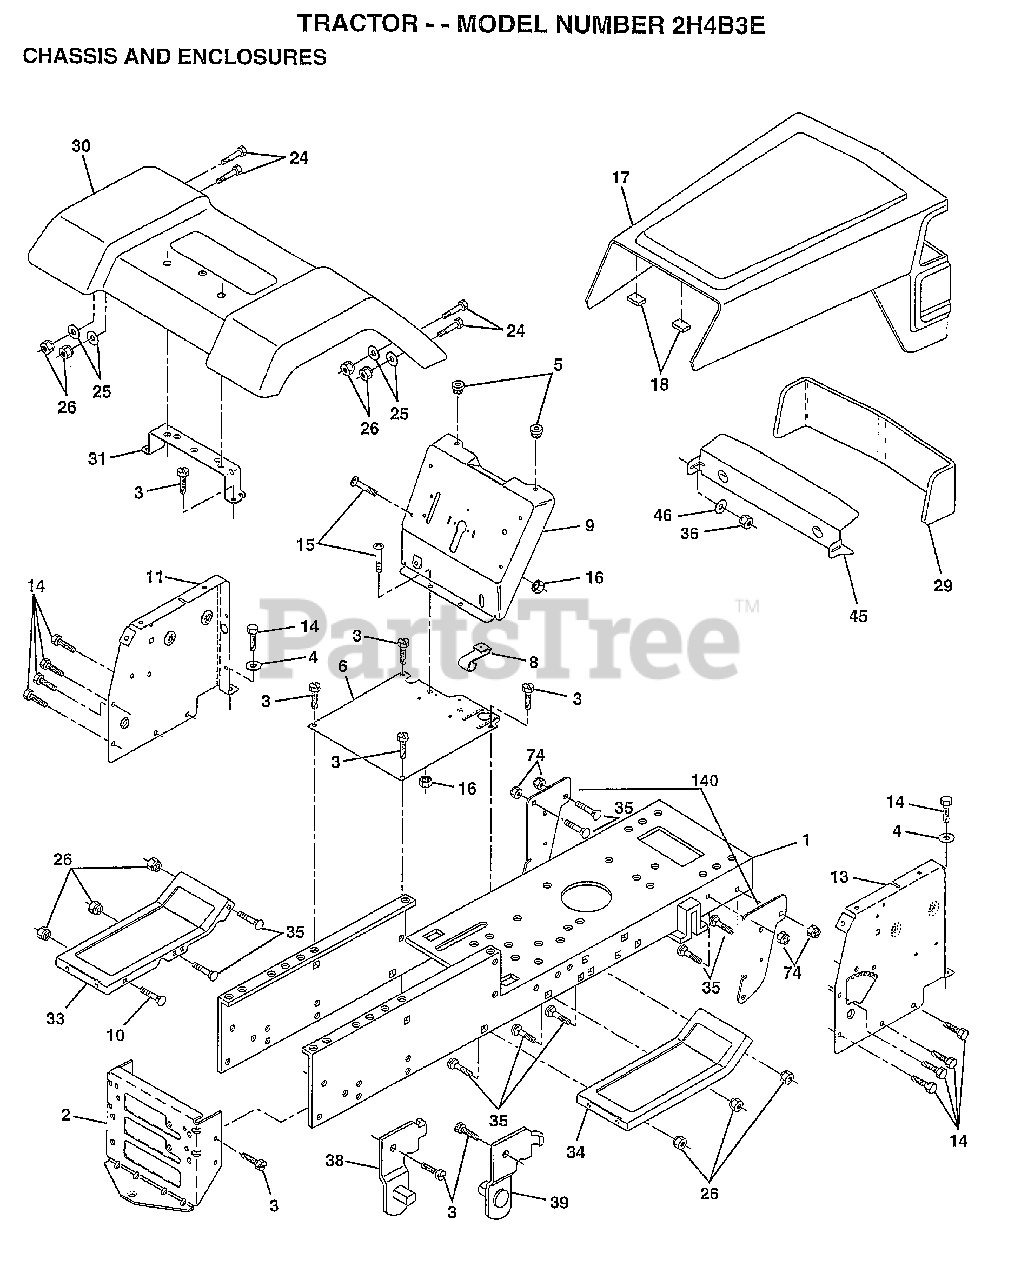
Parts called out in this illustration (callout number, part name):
1	CHASSIS WLDMT 11G
3	SCREW
4	WASHER
8	"CLIP,INSULATOR"
9	DASH.SLKSC.LT.1PC
11	PANEL.DASH.LH.
14	SCREW LT
15	SCREW
17	HOOD/GRILL ASM
24	BOLT
25	WASHER
26	NUT
30	FENDER
31	BRKT FENDER
33	FOOTREST LH
34	FOOTREST RH
35	BOLT
36	PAL NUT LT
38	BRACKET ASM LH
39	BRACKET ASM RH
46	RETAINER
